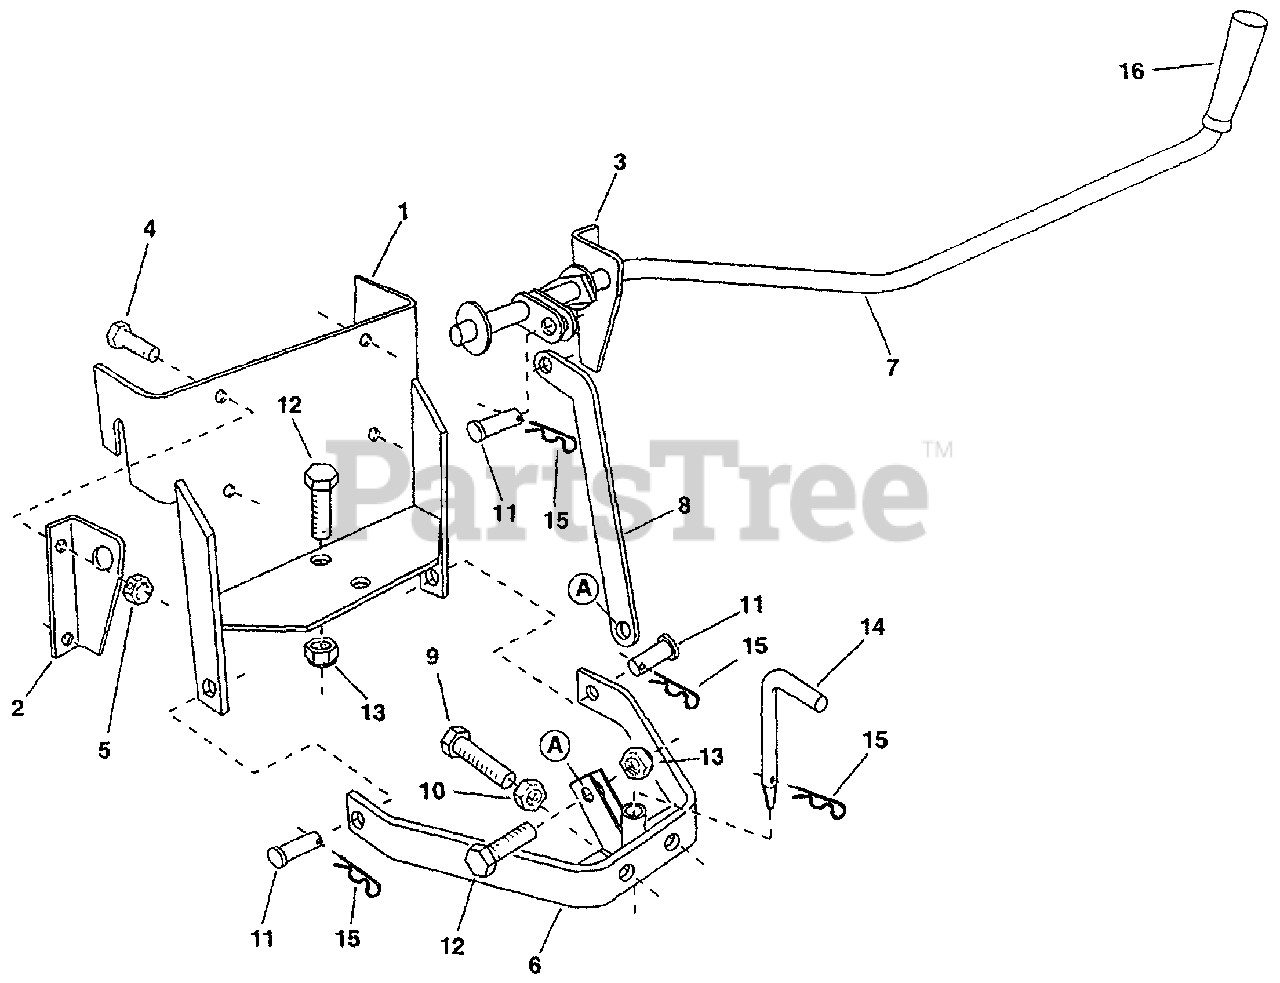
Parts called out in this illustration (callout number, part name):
1	Sleeve Hitch Frame Assembly
2	Pivot Bracket, L.H.
3	Pivot Bracket, R.H.
4	Bolt, Hex 3/8-16 x 1"
5	Hex Lock Nut, 3/8-16
6	Sleeve Hitch Lift Assembly
7	Lift Lever Assembly
8	Lifting Link Plate
9	Bolt, Hex 5/8-11 x 2-1/2"
10	Nut, Hex Jam 5/8-11
11	Clevis Pin, 5/8" x 1-3/4"
12	Bolt, Hex 5/8-11 x 1-3/4"
13	Nut, Nylock 5/8-11
14	Pin, Sleeve Hitch
15	Pin, Hair Cotter 5/32"
16	Grip, Plastic
